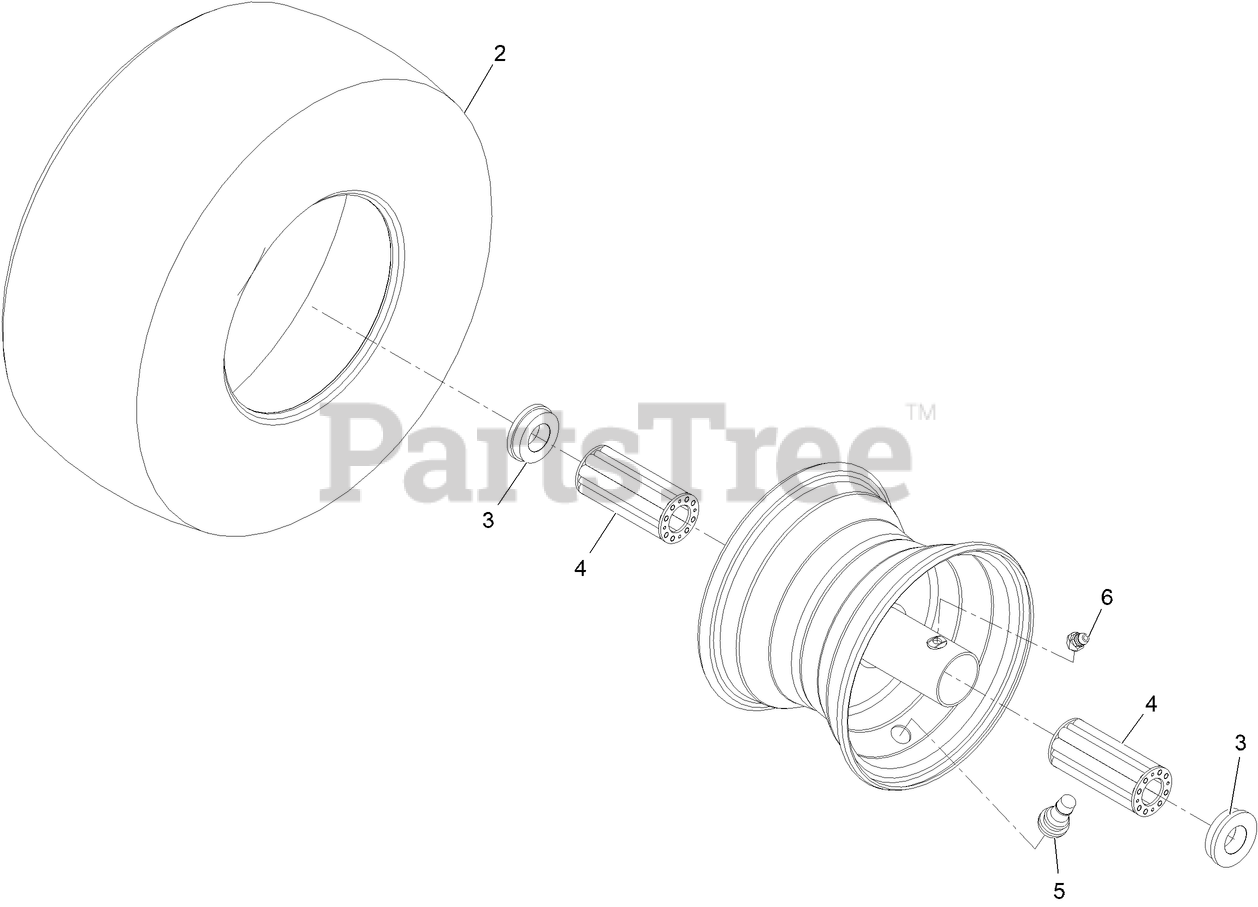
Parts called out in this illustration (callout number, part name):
3	BUSHING-FLANGE
4	BEARING-ROLLER, WHEEL
5	VALVE
6	FITTING-ZERK
